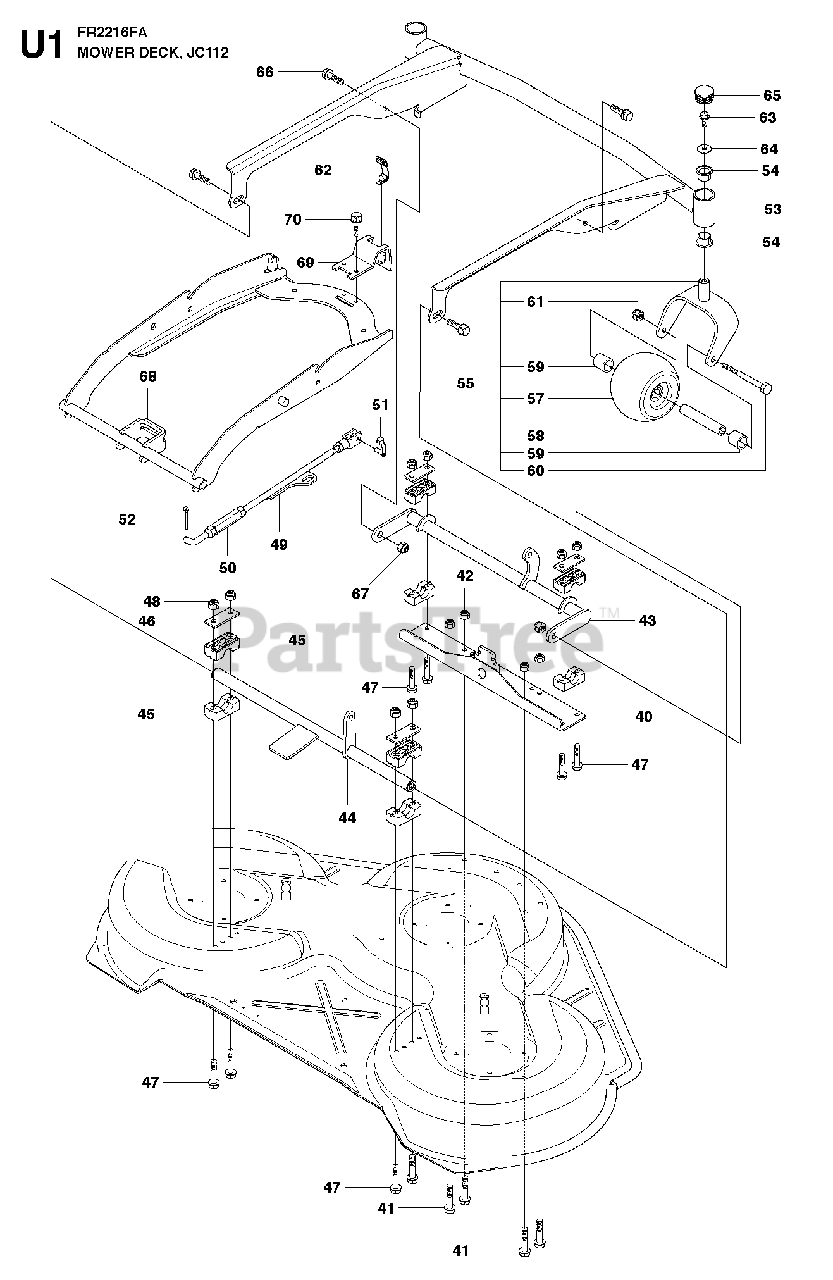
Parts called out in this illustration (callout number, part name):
42	LOCKNUT M8
48	LOCKNUT M8
49	PARALLELL ROD ASSY
50	PARALLEL ROD
51	RETAINER
52	SPLIT PIN
57	DECK ROLLER, FRONT
58	PIPE
59	SPACER
61	NUT
62	CLIP GRAY
67	LOCKNUT M8
